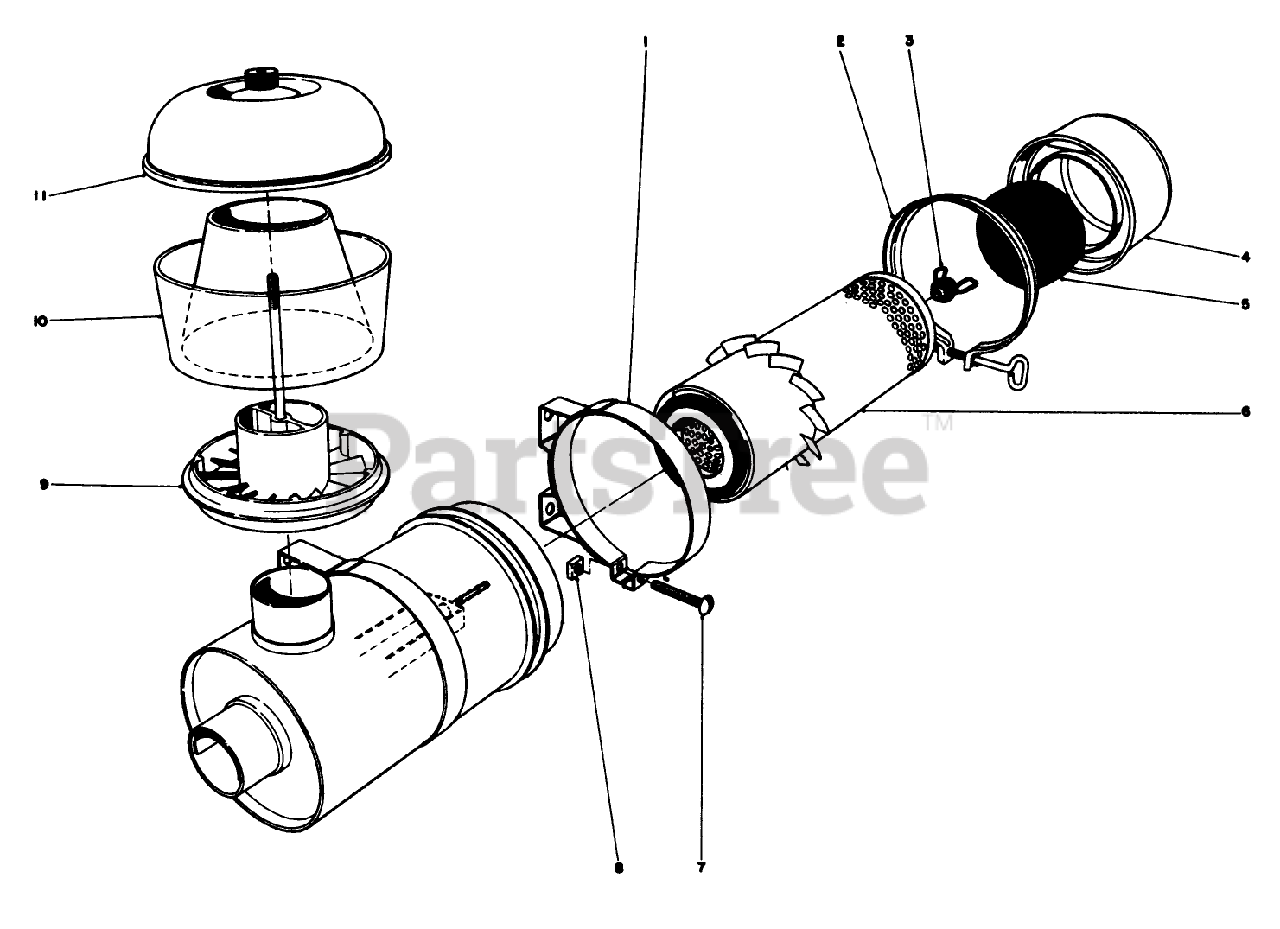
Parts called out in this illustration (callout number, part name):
1	MTG BAND ASM
2	CLAMP ASM
3	NUT ASM
4	CUP ASM
5	BAFFLE
6	ELEMENT ASM
7	SCREW
8	NUT-SQUARE
9	SLEEVE ASM
10	BOWL-CLEAR
11	COVER ASM
